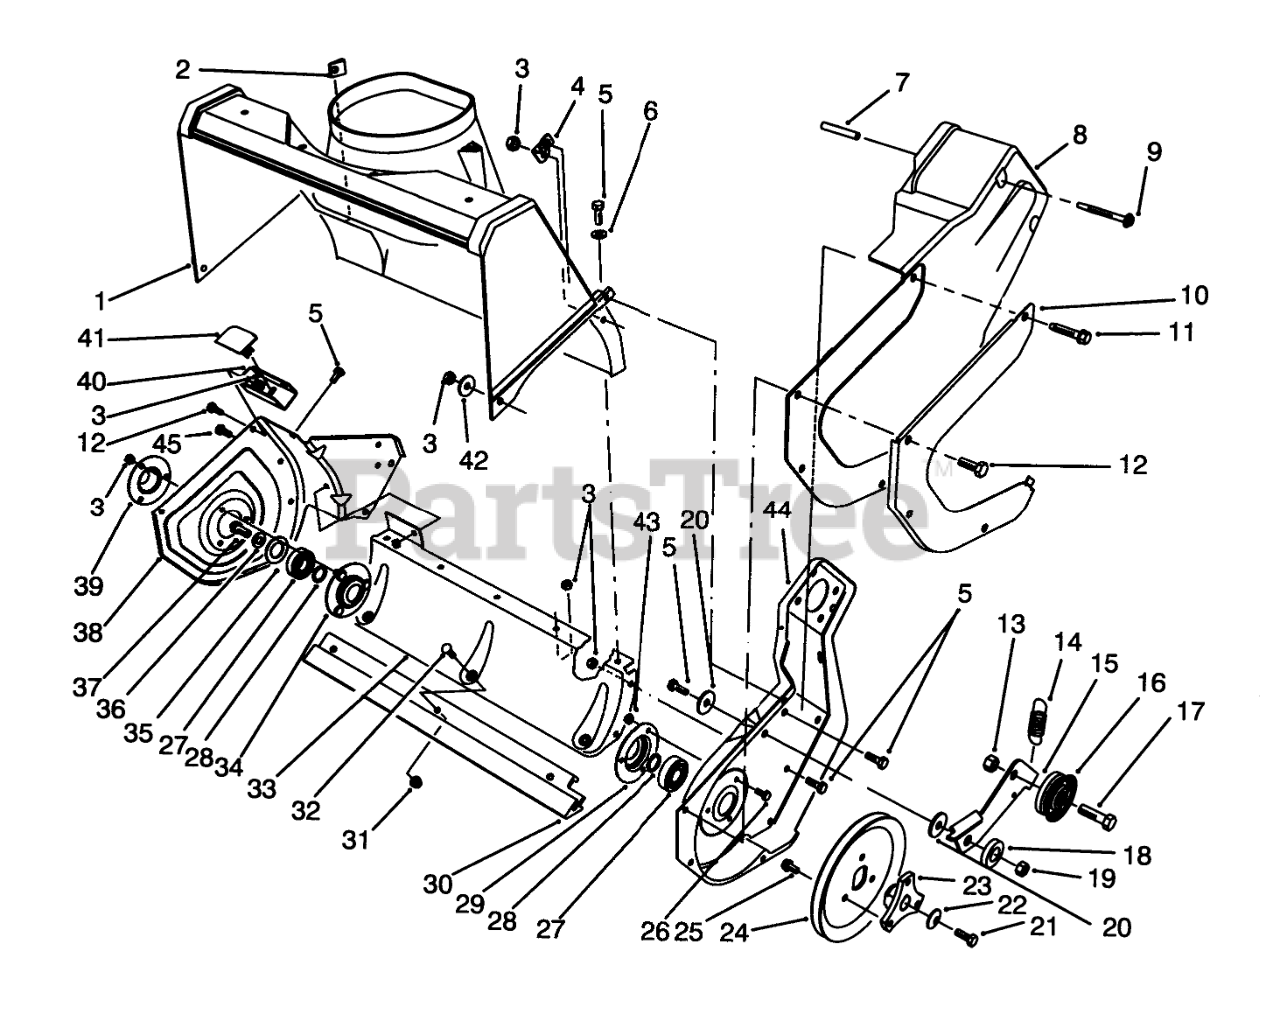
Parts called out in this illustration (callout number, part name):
1	HOUSING
2	SPEED NUT
3	NUT-LOCK, NI
4	BRACKET-HOUSING
5	SCREW-HH
6	WASHER-FLAT
7	TUBULAR SPACER
8	DRIVE COVER
9	SCREW-HWHTF
10	Guard-Drive Cover
11	SCREW-HWH, TAP
12	SCREW-HWH
13	NUT-LOCK, NI
14	SPRING-BRAKE
15	BRAKE ARM IDLER
16	PULLEY-IDLER
17	SCREW-HH
18	SPACER
19	NUT-LOCK, NI
20	WASHER-FLAT
21	SCREW-HH
22	WASHER-BELLEVILLE
23	HUB-MOUNTING, PULLEY
24	ROTOR PULLEY
25	SCREW
26	SCREW-SHH
27	BEARING-BALL
28	WASHER-THRUST
29	FLANGE-BEARING
30	SCRAPER
31	NUT-LOCK, HHF
32	SCREW-CARR
33	Housing-Lower
34	FLANGE-BEARING
35	WASHER-RUBBER
36	WASHER-FLAT
37	SCREW-HHF
38	Sideplate-R.H.
39	Trough
40	SIDEPLATE BRKT SUPT
41	BRACKET COVER
42	WASHER-FLAT
43	NUT-LOCK, NI
44	Sideplate L.H.
45	SCREW-HH
